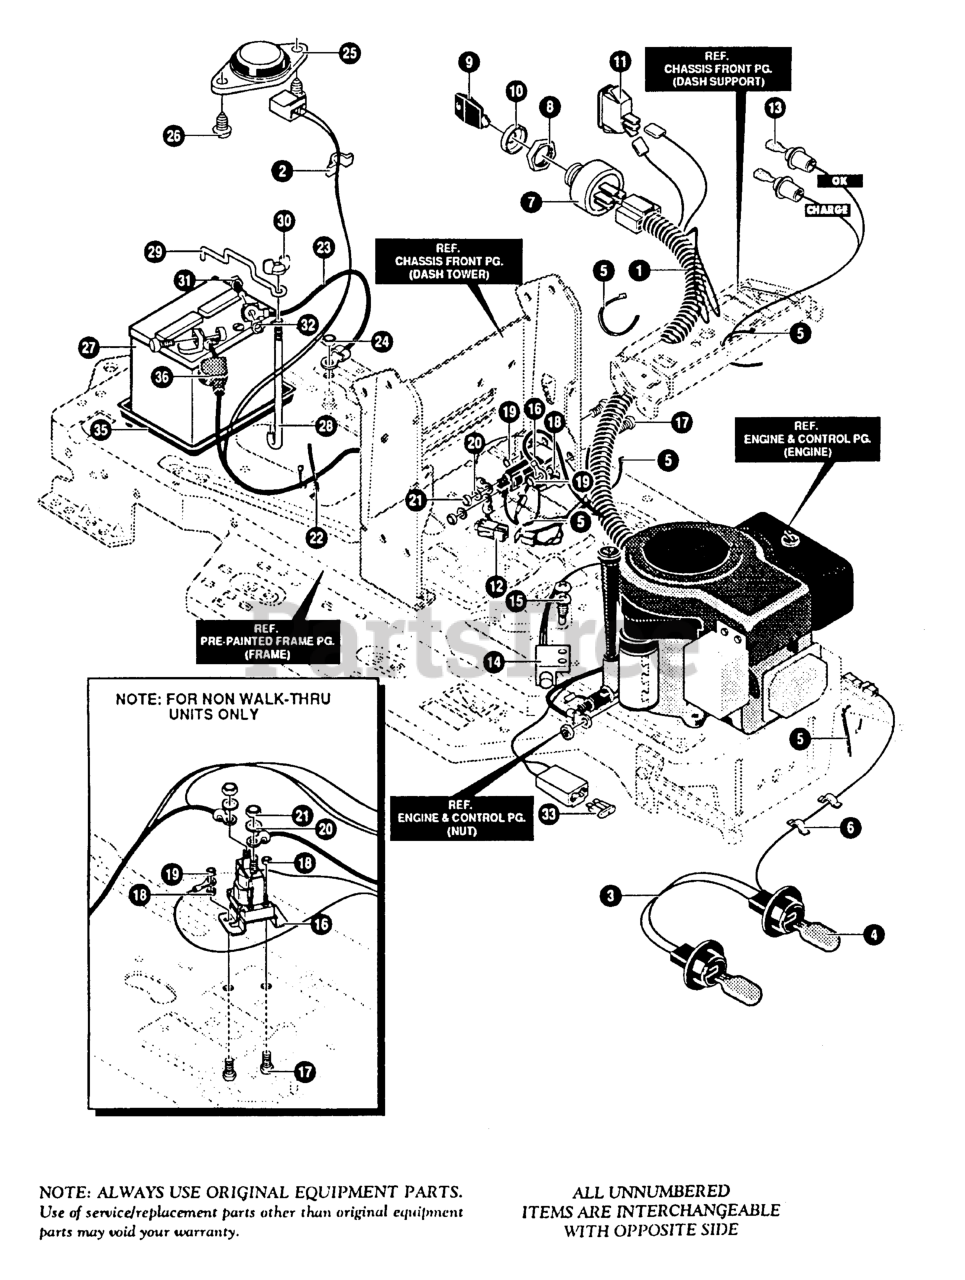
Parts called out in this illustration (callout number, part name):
1	HARNESS, WIRE
2	PRESS CLIP
3	ASSEMBLY, LIGHT WIRE
4	BULB, HEADLAMP
5	TIE, CABLE
6	PRESS CLIP
7	SWITCH-IGNITION
8	NUT, 5/8-8
9	KEY, IGNITION
10	BOOT, IGNITION SWITCH
11	LIGHT SWITCH, PANEL MOUNT
12	SWITCH, DOUBLE POLE
13	BULB, INDICATOR
14	SWITCH, SCREW MOUNT
15	SCREW, #12 X .50
16	SOLENOID
17	SCREW, 1/4-20 X .75
18	NUT, 1/4-20
19	NUT, 1/4-20
20	WASHER, .320 X .61 X .03
21	NUT, 5/16-14
22	TIE, CABLE
23	WIRE, GROUND
24	NUT, 5/16-18
25	SWITCH, SEAT
26	SCREW, 1/4-20 X .38
27	BATTERY, 12V
28	ROD, BATTERY
29	ROD, BATTERY, TOP
30	NUT, WING 1/4-20
31	SCREW, 1/4-20 X .75
32	NUT, 1/4-20
35	TRAY - BATTERY
36	BOOT, BATTERY
